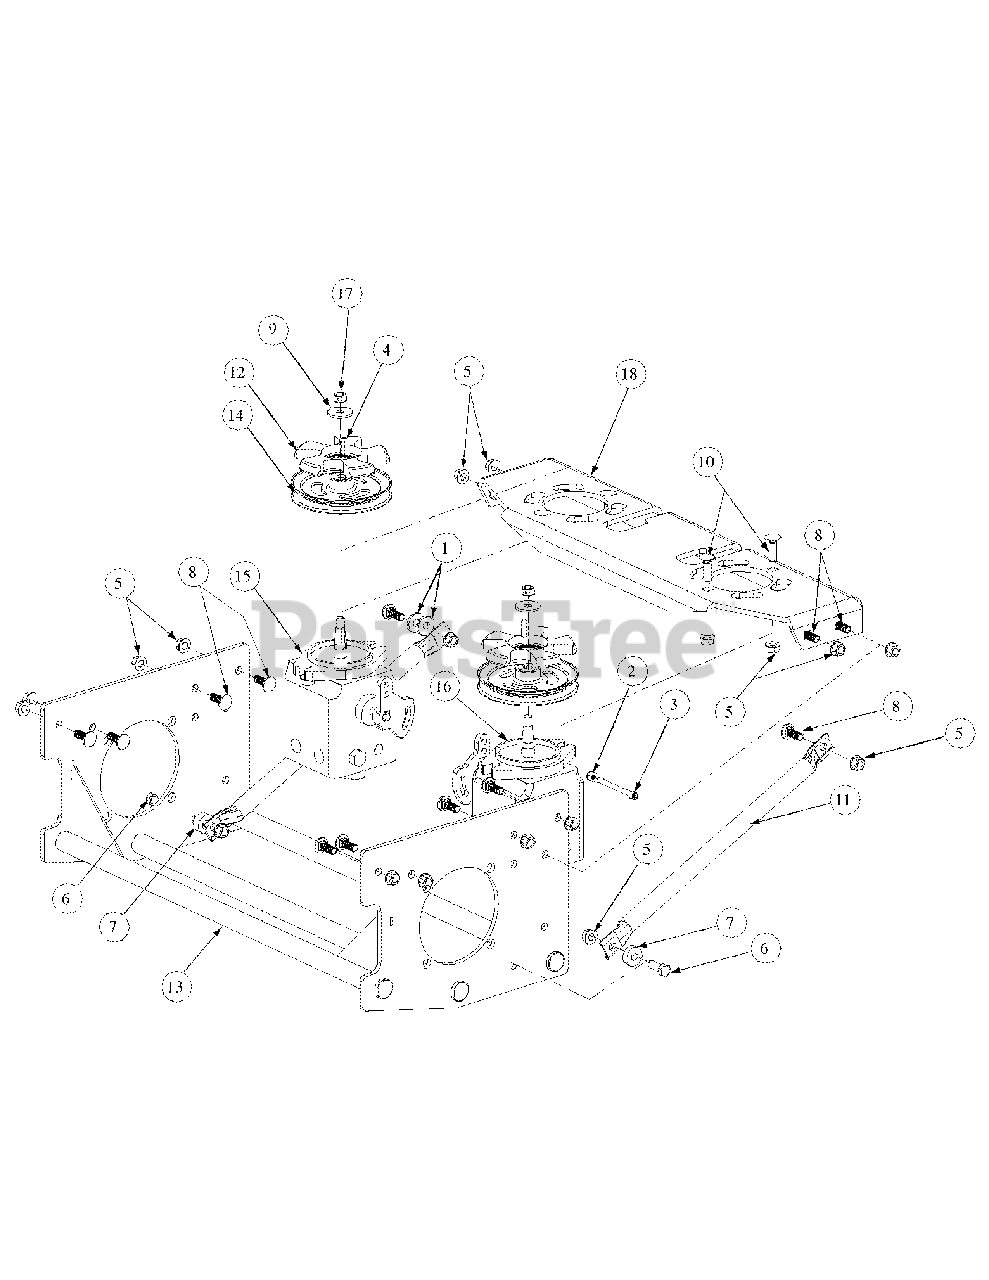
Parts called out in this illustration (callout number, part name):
1	Washer lock 3/8 zinc
2	Lock Nut, Nylon Insert, 1/4-20
3	Socket Head Cap Screw, 1/4-20 x 2-1/2
4	Key, 3/16" x 7/8"
5	Flange Lock Hex Nut, 3/8-16
6	Hex Cap Screw, 2/8 -16 x 1.25
7	Spacer, .406 ID x 1.00 OD x .38
8	Carriage Bolt, 3/8-16 x 1
9	Flat Washer, .411 x 1.25 x .100
10	Carriage Screw, 3/8-16 x 1.25
12	Hydro Pulley Fan
13	Hydro Motor Frame Assembly
14	Hydro Pulley Pump
15	Hydro Pump, LH
16	Hydro Pump, RH
17	Hex Nut, 3/8-24
18	Hydro Pump Mounting Weldment
